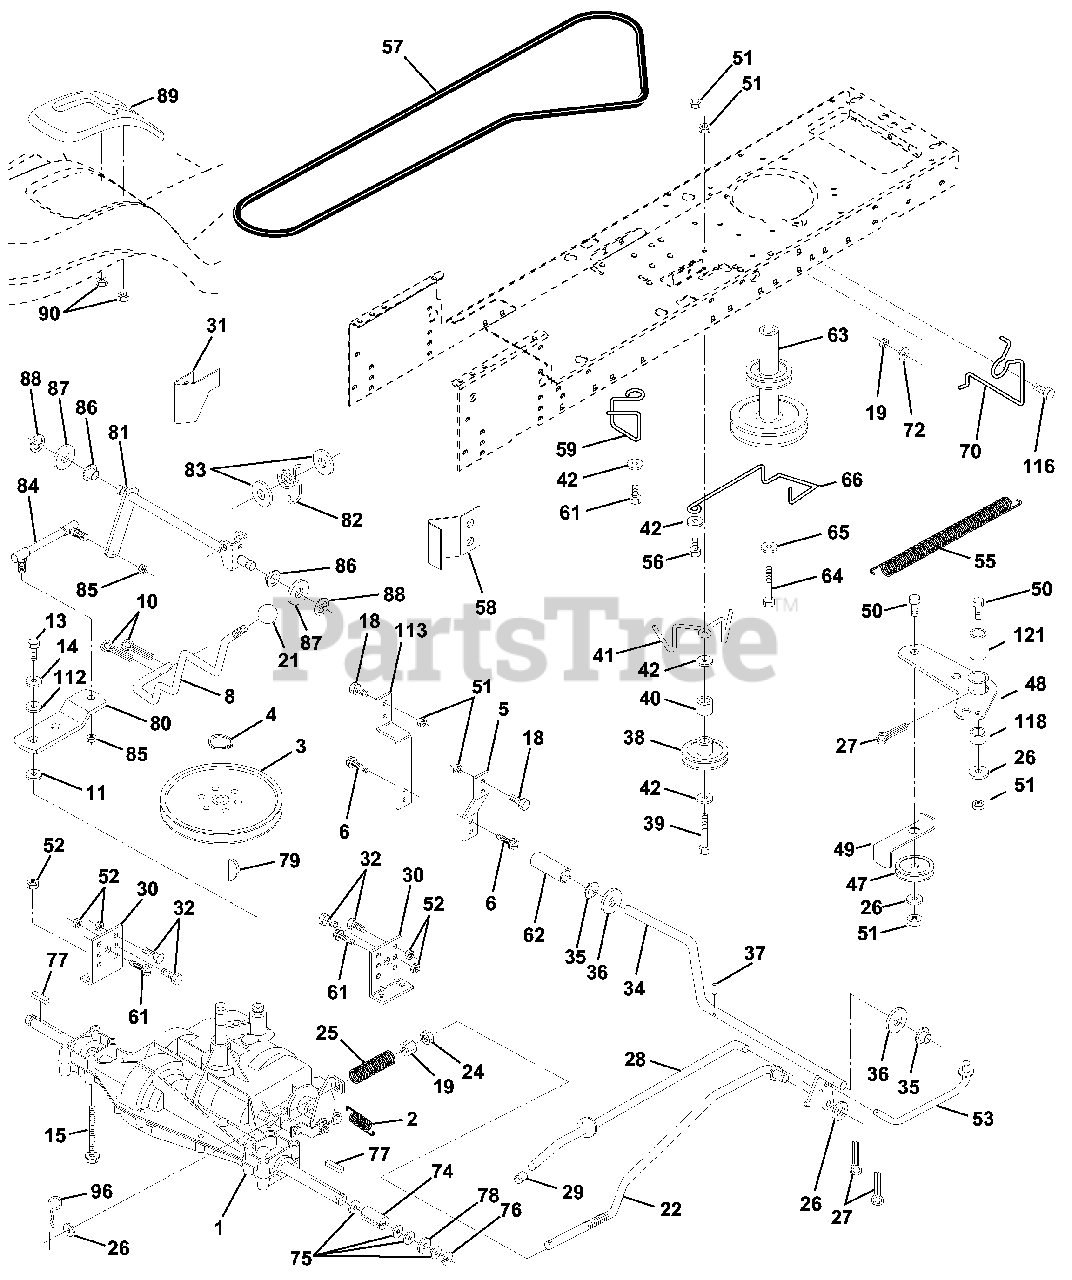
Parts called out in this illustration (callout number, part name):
2	Spring Return Brake T/a Zinc
3	Pulley Transaxle 18" tires
4	Ring Retainer # 5100-62
5	Strap Torque 30 Degrees
6	Screw Thdrol 5/16-18 X 3/4 TYT
8	Rod Shifter
10	Pin Cotter 1/8 X 1 Cad
11	Washer Plate Shf 388 Sq Hole
13	Bolt 1/4-28 Unf Gr 8 W/Patch
14	Washer Lock Hvy Helical 1/4
15	Bolt Hex 5/16-18 Gr. 5
18	Bolt, Fin Hex 3/8-16 UNC x 1 Gr. 5
19	Nut Lock 3/8-16 Unc
22	Rod Brake Blk Zinc 26 840
24	Nut Hex Jam 3/8-16 Unc
25	Spring Rod Brake 2 00 Zinc
26	Washer 13/32 X 13/16 X 16 Ga
27	Pin Cotter 1/8 X 3/4 Cad
28	Rod Brake Parking LT/YT
29	Cap Brake Parking Black
30	Bracket Mtg Transaxle
31	Keeper Belt LH LT 14 Ga
32	Bolt Hex Hd 5/16-18unc X 3/4
34	Shaft Asm Pedal Foot
35	Bearing Nylon Blk 629 Id
36	Washer 21/32 X 1 X 16 Ga
37	Pin Roll 3/16 X 1"
38	Pulley Idler Flat
39	Bolt Fin Hex 3/8-16unc X 2-3/4
40	Spacer Split 395 X 59 Bzp
41	Keeper Belt Retainer Idler Foolproof
42	Washer 13/32 X 13/16 X 12 Ga
47	Pulley Idler V Groove Plastic
48	Bellcrank Asm
49	Retainer Belt Style Spring
50	Bolt Hex Hd 3/8-16unc X 1-1/2
51	Nut Crownlock 3/8-16 Unc
52	Nut Crownlock 5/16-18 Unc
53	Link Clutch
55	Spring Return Clutch 6 75
56	Bolt Fin Hx 3/8-16 X 1/4
57	V-Belt Ground Drive 95 25
58	Keeper Belt RH LT Pnt/zinc 16g
59	Keeper Belt Span Ctr
61	Screw Thdrol 3/8-16x3/4 Ty-tt
62	Cover Pedal Blk Round
63	Engine Pulley LT/YT
64	Bolt Hex
65	Washer Lock Hvy Hlcl Spr 7/16
66	Keeper Belt Engine Foolproof
70	Guide Belt Mower Drive RH
72	Washer 13/32 X 1-1/4 X 12 Ga
74	Spacer Axle
75	Washer 25/32 X 1 1/4 X 16 Ga
76	E-ring #5133-75
77	Key Square 2 0 X 1845/ 1865
78	Washer 25/32 X 1-5/8 X 16 Ga
79	Key Woodruff #9 3/16 x 3/4
81	Shaft Asm Cross 20"t
82	Spring Torsion T/a
83	Washer 17/32 X 3/4 X 16 Ga
84	Rod Shift
85	Nut Lock Center 1/4 - 28 FNTHD
86	Bushing Rod Strg 629/632 Id
87	Washer 21/32 X 1-1/4 X 16 Ga
88	Ring Klip #5304-62
89	Console Shift STLT
90	Nut Self-thd Wsh-hd 1/4 Zinc
112	Washer 9/32 x 3/4 x 10 Ga.
113	Strap Torque LT
116	Bolt Rdhd Sq Neck 3/8-16 x 1.25
118	Spacer Bellcrank
121	Nyliner Clutching STL
